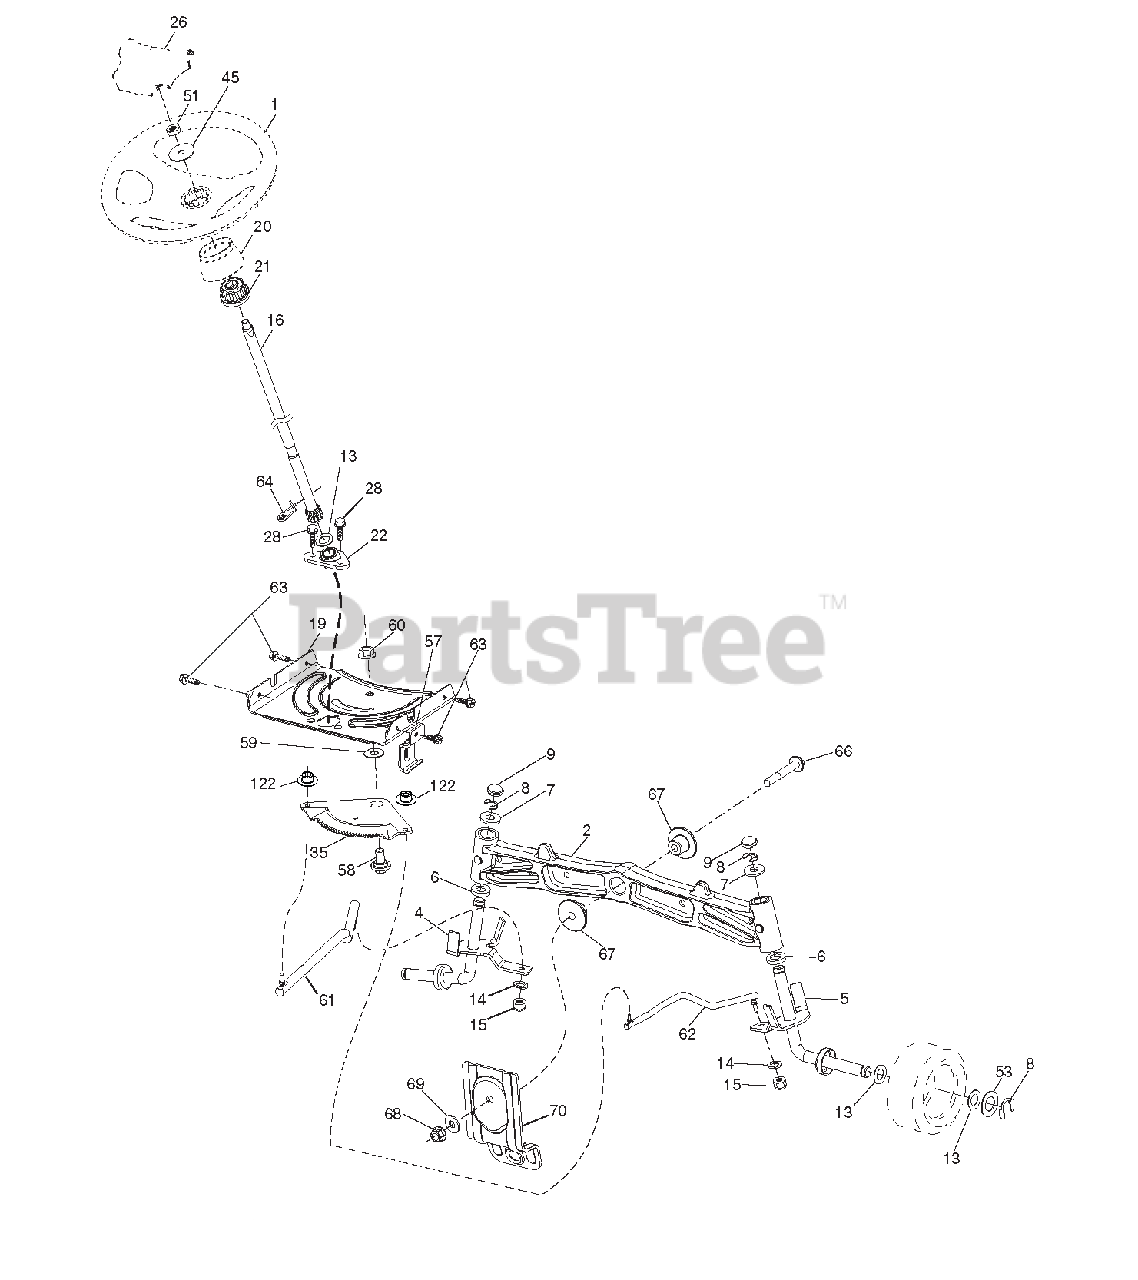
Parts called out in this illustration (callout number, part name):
1	WHEEL STEERING
2	AXLE.CAST IRON
4	SPINDLE.WELDED.LH.15"TEX
5	SPINDLE.WELDED.RH.15"TEX
6	WAHSER THRUST .75 X 1.230
7	WASHER.25/32 X 1-5/8 X 16GA.
8	RING.KLIP.#T5304-75
9	CAP.SPINDLE.FR.TOP.BLK.
13	WASHER.25/32 X 1 1/4 X 16 GA.
14	Washer, Lock 3/8
15	NUT.CROWNLOCK.3/8-24
16	SHAFT.STEER.3/4 TEX.NON-PLATED
19	PLATE.STEER.DDL.NLT/NGT
20	BOOT.STEERING.
21	ADAPTER.WHEEL.STRG..760
22	STEERING SUPT. LOWER
26	CAP WHEEL STEERING HRS/SRS BLK
28	SCREW.HEXWSH THDR3/8-16X3/4.BL
35	GEAR SECTOR.PLATE.DDL.NLT/NGT
45	WASHER.11/32ID X2 3/8OD X 12GA
51	NUT.HEX.JAM.TOPLOCK.1/2-20 UNF
53	WASHER.HARDEN..793 X 1.637X060
57	BRACKET.UPSTOP.GT/LT.TEX
58	BOLT.SHOULDER.SECTOR.PIVOT.CFM
59	WASHER.THRUST.SECTOR.STEER.NLT
60	NUT.FLANGE LOCK.5/8-11
61	DRAGLINK.LH.BALLSTUD.DDL.
62	DRAGLINK.RH.BALLSTUD.DDL
63	SCREW.5/16-18X3/4.SMGML.TAP/BL
64	RETAINER.CLIP.SPRING.STEERING
66	BOLT.HEX.FGHD.7/16-14 X 3.SERR
67	BUSHING.PM.FRONT AXLE
68	NUT.LOCK.FLANGE.7/16-14.GR5
69	WASHER.1.5 X .505 X .118
70	BRACKET.DECK.SUSPENSION.FRONT
122	CAP GEAR SECTOR
